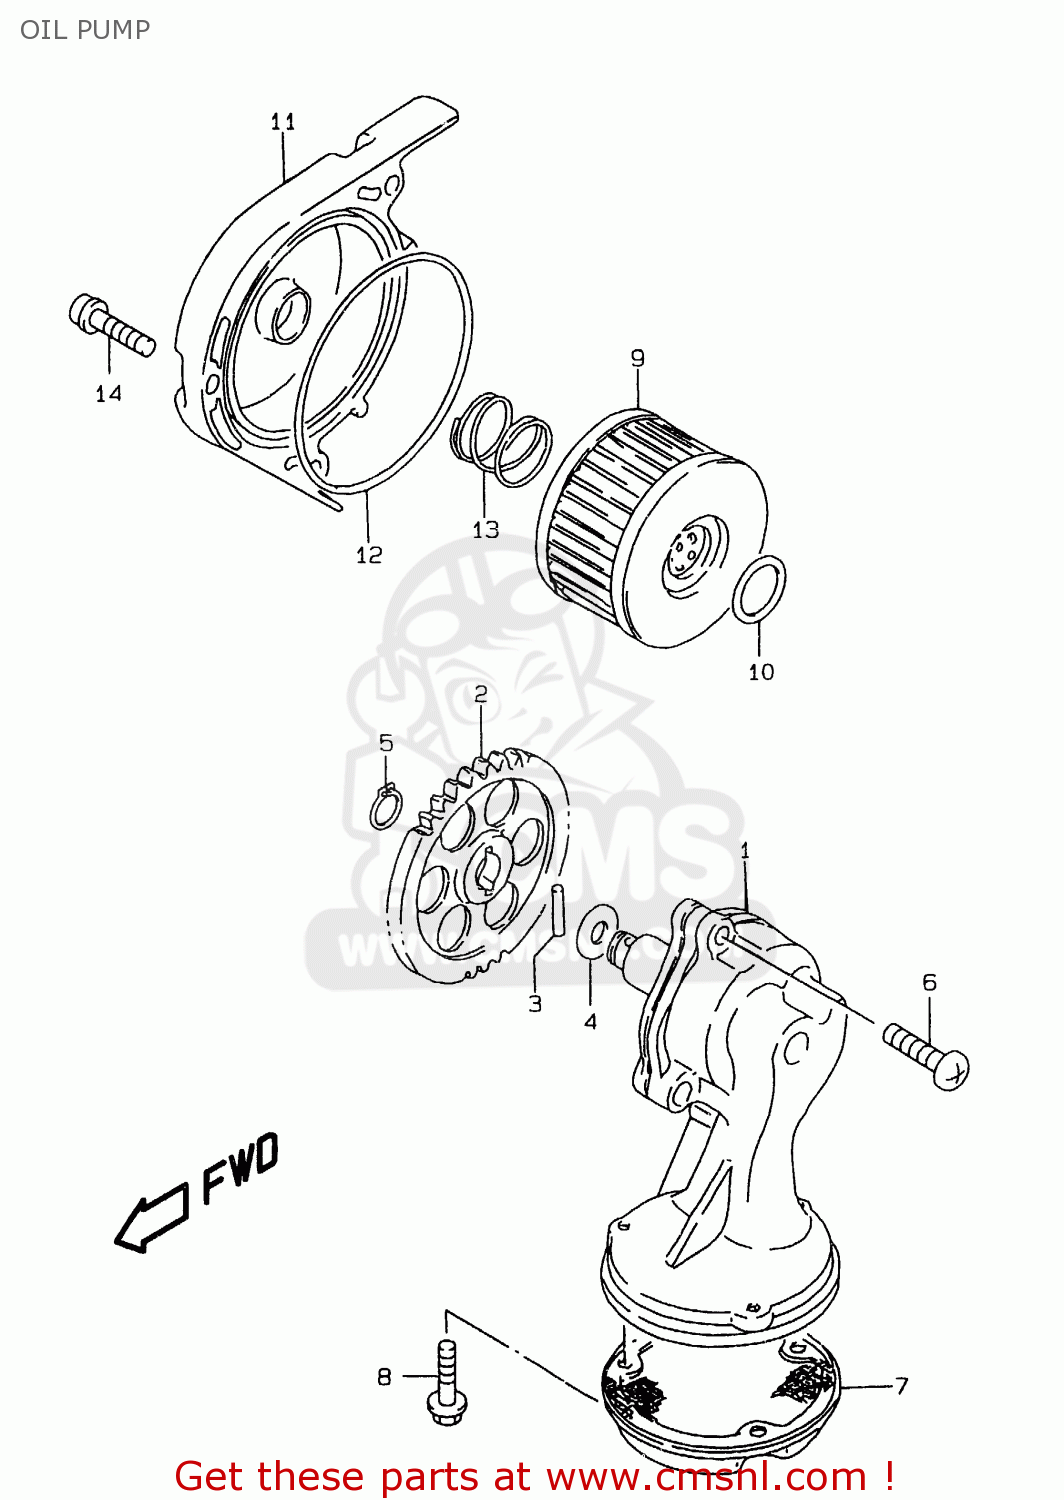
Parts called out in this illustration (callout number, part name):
1	PUMP ASSY,ENGINE OIL
2	GEAR,ENG OIL PUMP DRIVEN
3	PIN(4X15.8)
4	SHIM
5	CIRCLIP,10MM
6	SCREW
7	STRAINER,ENGINE OIL
8	BOLT
9	FILTER,ENGINE OIL
10	O RING(D:2.4,ID:15.8)
11	CAP,OIL FILTER
12	O RING(D:2.4,ID:73)
13	SPRING
14	BOLT
